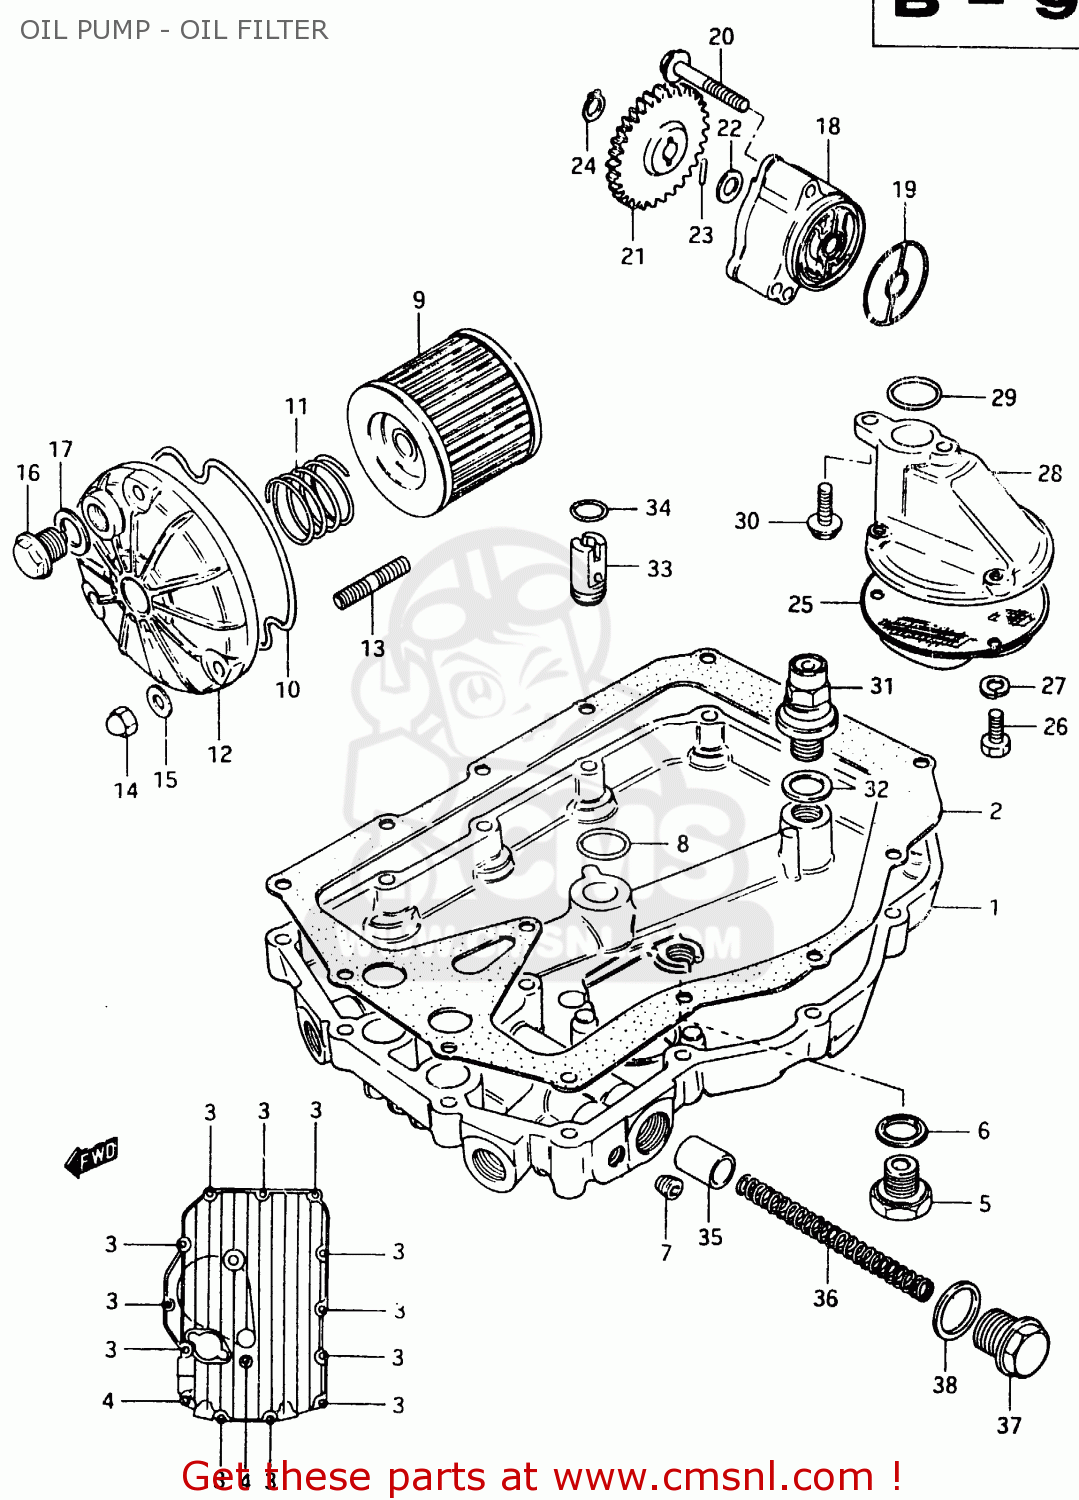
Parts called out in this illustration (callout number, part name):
1	PAN,OIL
2	GASKET,OIL PAN (MCA)
3	BOLT 6X30
4	BOLT (6X40)
5	PLUG
6	GASKET(14X19.2X2) (NAS)
7	PLUG
8	O RING(D:3.2,ID:15.8)
9	FILTER ASSY,ENGINE OIL
10	O RING,OIL FILTER CHAMBER CAP
11	SPRING
12	CAP,OIL FILTER
13	STUD 6X20
14	NUT 6MM
15	WASHER
16	PLUG(14X12)
17	GASKET(14X19.2X2) (NAS)
18	PUMP ASSEMBLY,OIL
19	O RING,OIL PUMP
20	BOLT
21	GEAR,OIL PUMP DRIVEN
22	SHIM
23	PIN(4X15.8)
24	CIRCLIP
25	STRAINER,ENGINE OIL
26	BOLT
27	LOCK WASHER
28	PROTECTOR,OIL STRAINER
29	O RING(D:3.2,ID:17.8)
30	BOLT,REAR
31	REGULATOR ASSY,ENGINE OIL
32	WASHER
33	VALVE ASSEMBLY,PISTON OIL
34	O RING(D:1.3,ID:9.8)
35	PLUNGER,CONTROL
36	SPRING
37	PLUG
38	O RING(D:2.4,ID:16.8)
